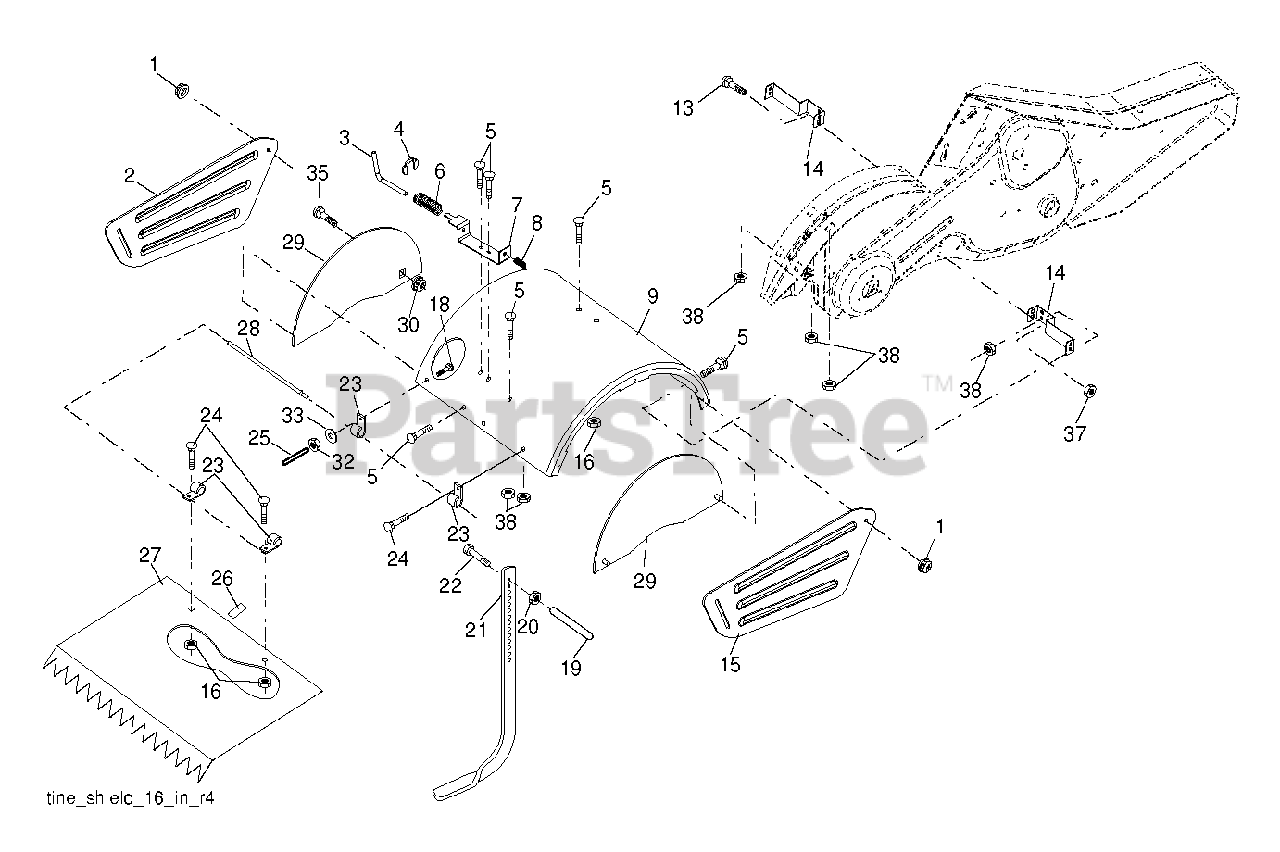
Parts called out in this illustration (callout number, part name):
1	NUT LOCK HEX FLANGE 5/16-18
3	STAKE PIN TI
4	RING, KLIP
5	BOLT, RDHD SQNK 5/16-18 X 3/4
6	SPRING TI
8	SPRING CRT
9	SHIELD,TINE**
13	BOLT.CARRIAGE.5/16-18
14	BRACKET.TINE.SHIELD.TILLER.BLA
16	NUT T
19	GRIP CRT
20	NUT.HEX.3/8-16UNC
22	BOLT.375-16
23	HINGE CRT
26	PAD IDLER TI
27	SHIELD.LEVELING
28	PIN.HINGE.TILLER
29	SHIELD.SIDE.PNT.421
30	LOCKNUT-FLANGE 5/16-18
32	NUT
33	LOCKWASHER
35	BOLT
37	NUT.71038.31-18.HEX.NYLOCK
